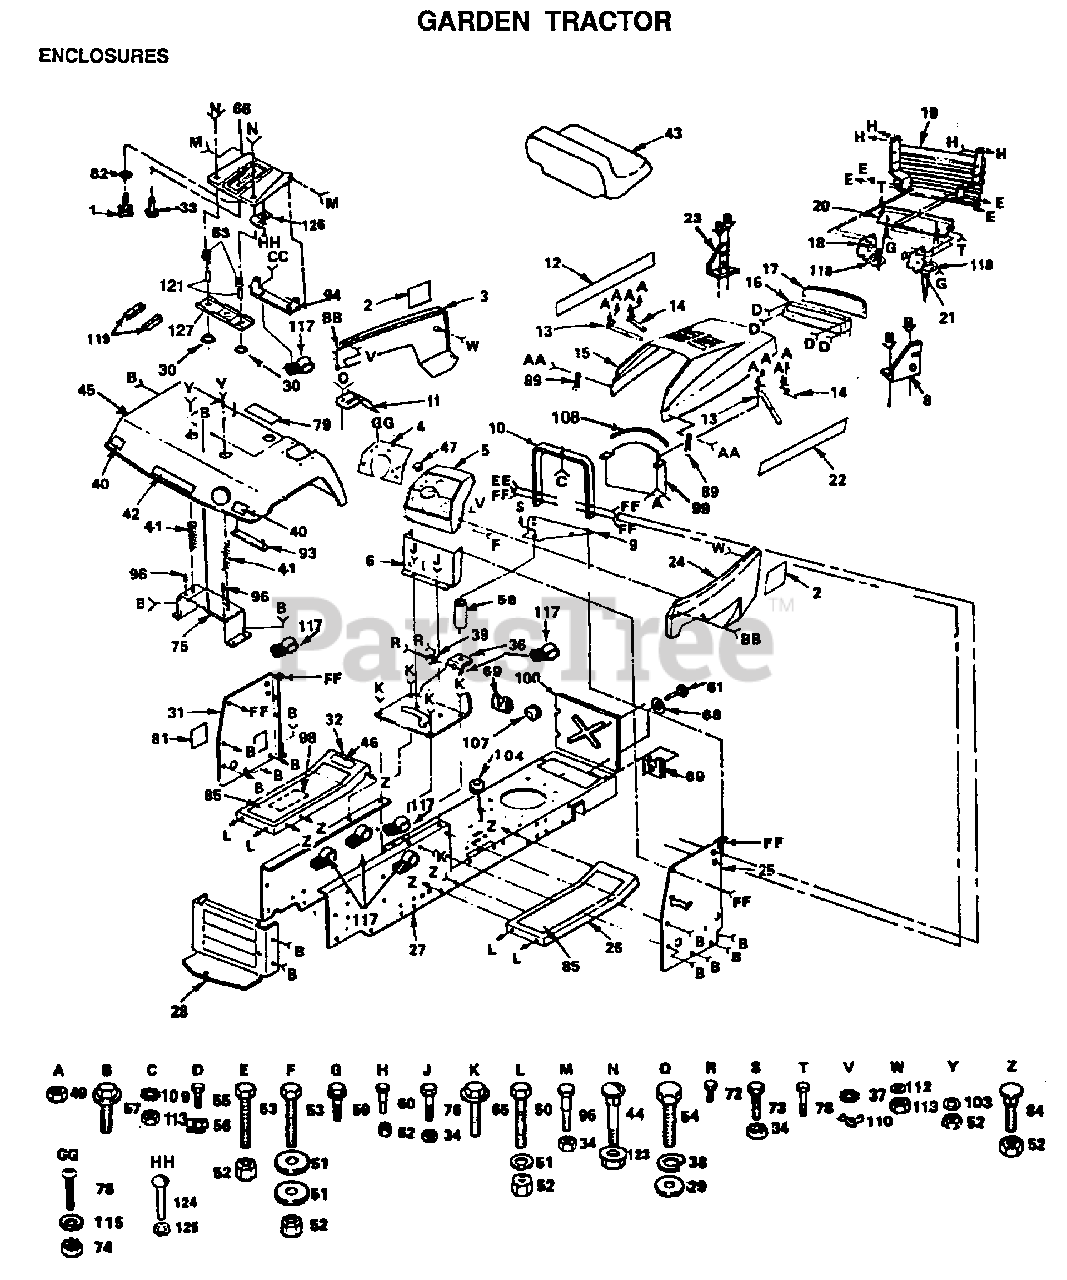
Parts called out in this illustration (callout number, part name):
6	LOWER DASH
8	SUPPORT RH YTH
11	CONSOLE SHIFTER
12	DECAL HOOD LH
17	LENS LT
18	SUPPORT LH YTH
21	SUPPORT RH YTH
23	SUPPORT LH YTH
27	CHASSIS ASSY
28	DRAW BAR
29	WASHER
30	BUSHING
31	PANEL DASH LH
32	FOOTREST LH YT
37	LOCKWASHER GT
38	"WASHER,LOCK"
40	REFLECTOR-TAIL YT
41	SPRING COMPRESSIO
44	BOLT
46	DECAL T
47	PLUG BUTTON T
49	NUT
51	WASHER
53	BOLT
54	SCREW
56	"""J"" FASTENER LT"
57	SCREW
58	SPACER
59	SCREW
61	STUD.1/4.TURN
63	SPRING
65	SCREW LT
68	RETAINER LT
69	RECEPTACLE LT
73	BOLT
76	SCREW
78	SCREW
79	DECAL
81	COVER ACCESS
82	WASHER
84	BOLT
85	PAD FOOTREST T
88	WELDNUT
89	HOOD LATCH T
96	NUT-PUSH YT
99	VERTICAL BAFFLE
103	WASHER
104	SNAP BUSHING T
108	STRIP - FOAM
112	WASHER PM
115	WASHER
117	CLIP T
118	WASHER
119	STRIP FORM
121	SPACER SPLIT
127	BRKT SWITCH
